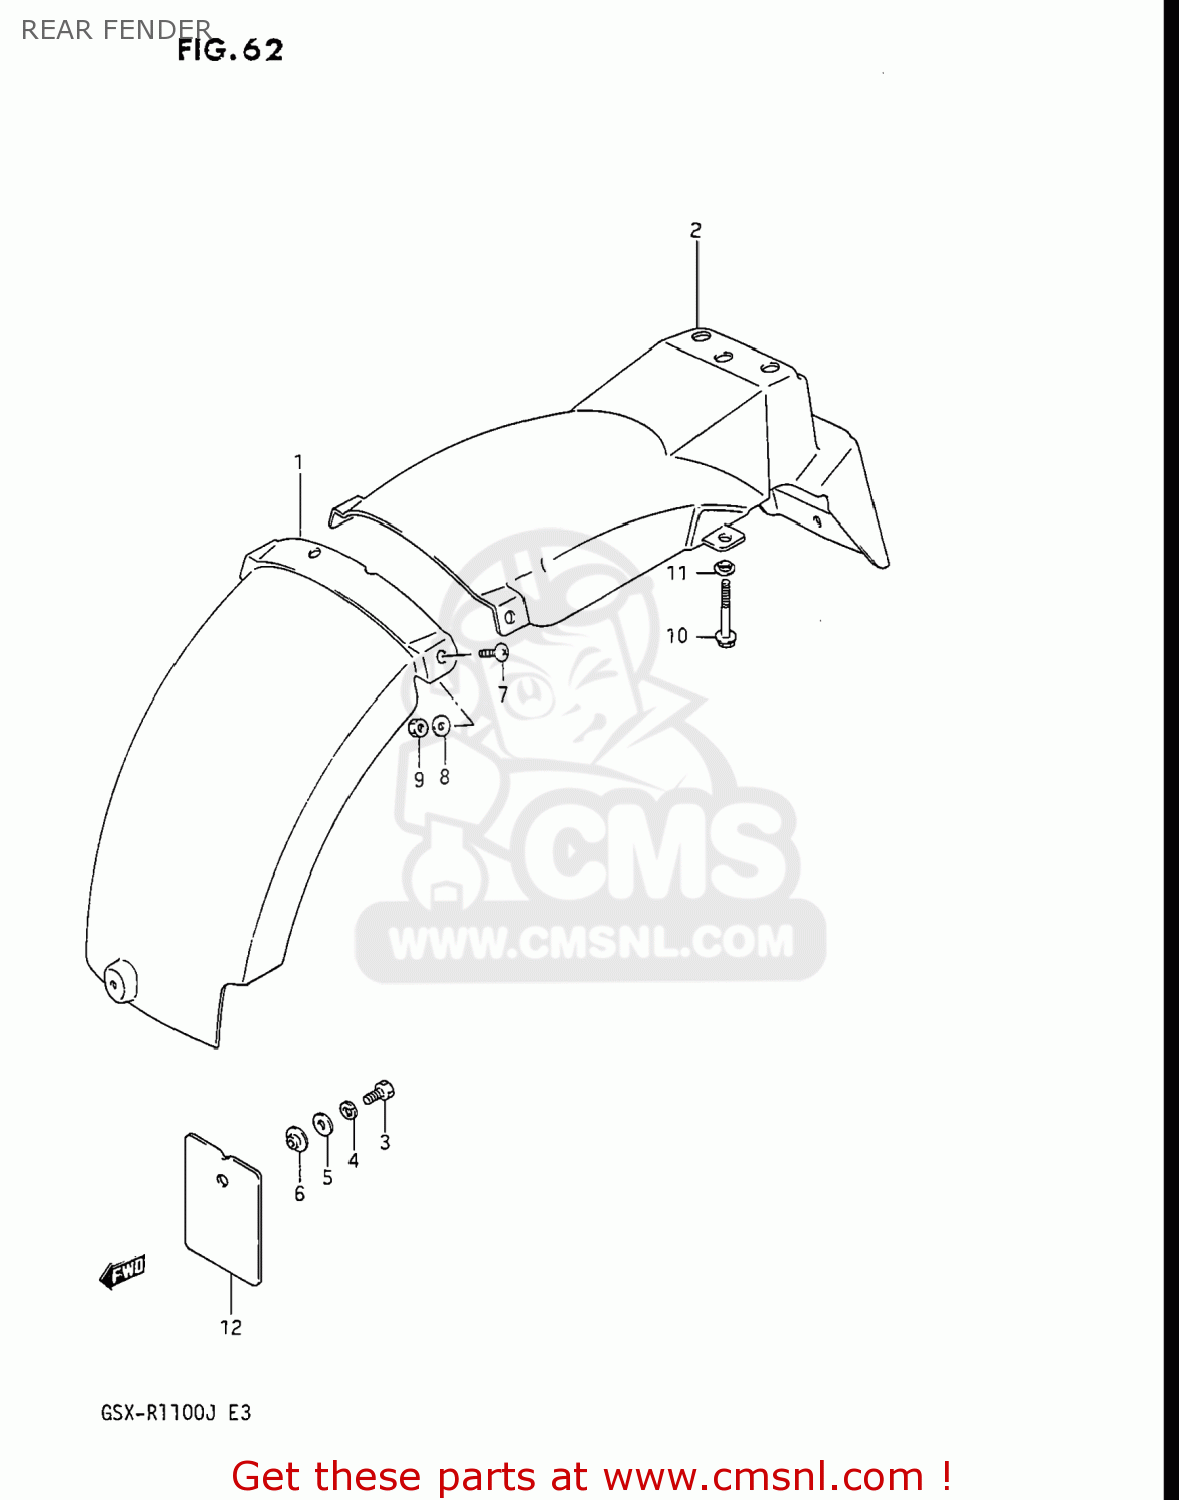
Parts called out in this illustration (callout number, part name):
1	BODY,REAR FENDER,FRONT
2	FENDER,REAR
3	BOLT
4	WASHER,LOCK
5	WASHER
6	WASHER
7	SCREW
8	WASHER
9	NUT 6MM
10	BOLT
11	WASHER
12	MUD GUARD,REAR FENDER,FRONT
